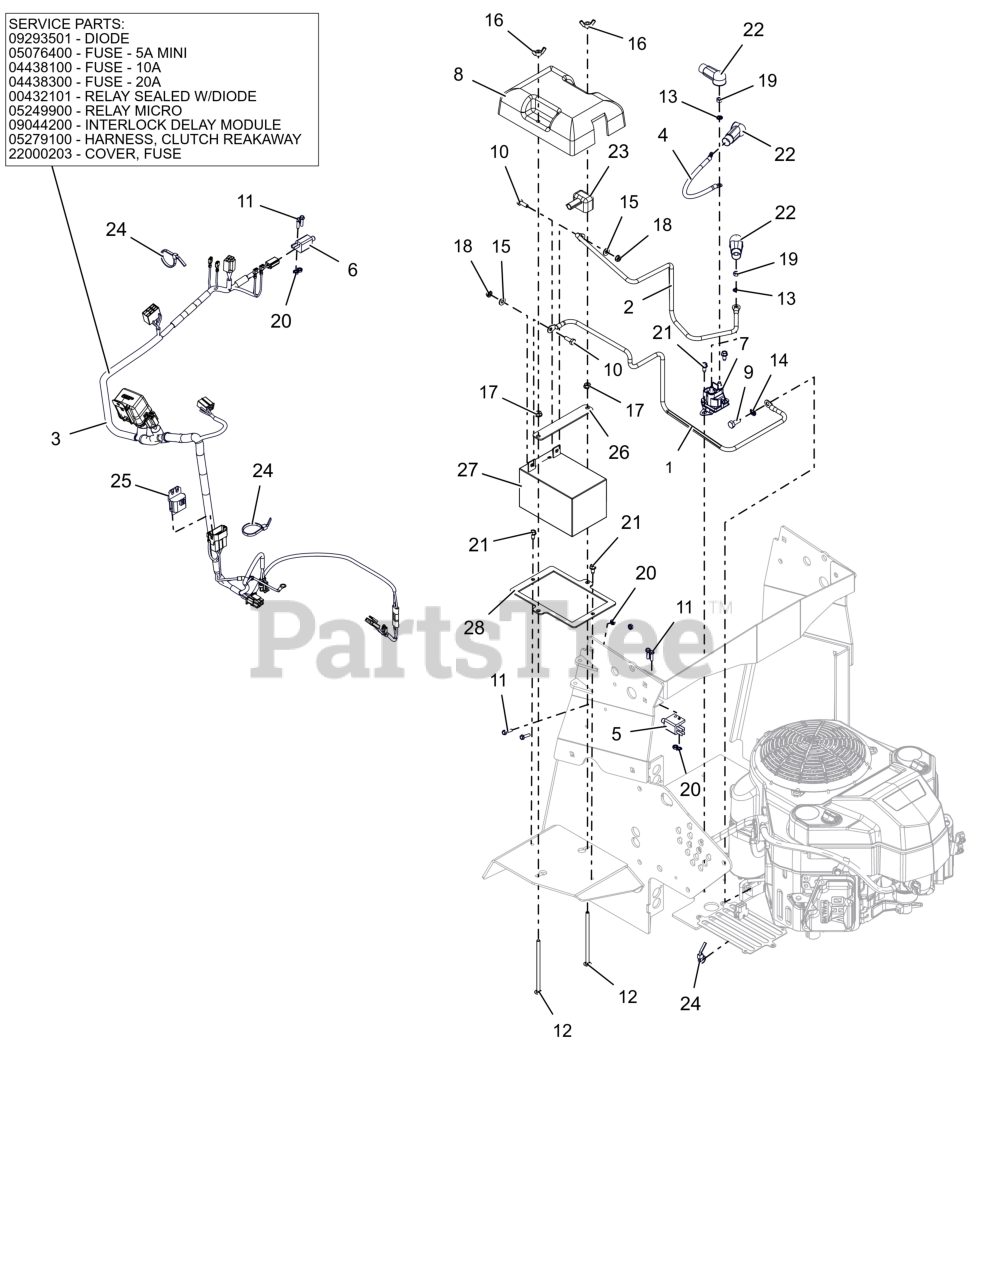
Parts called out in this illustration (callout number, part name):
1	CABLE, NEGATIVE BATTERY
2	CABLE, RED- .31X30.00 (6) X .25
3	HARNESS- WIRING
4	CABLE-POSITIVE BATTERY 9.00"
5	SWITCH- DOUBLE POLE N.O./N.O.
6	SWITCH- SINGLE POLE N.O.
7	SOLENOID, STARTER (SEALED)
8	COVER, BATTERY
9	BLT, HEX M8-1.25X20 G8.8 ZCC
10	BLT, HEX .25-20X.75 G5 ZCC
11	BLT, HWH #10-24X.75 ZCC
12	BLT- RHSN .25-20X5.0 ZCC
13	WSHR,LK-EXT.262X.502X.026 ZCC
14	WSHR,LK-EXT .326X.599X.031 ZCC
15	WSHR,FLT .281X.625X.065 ZCC
16	NUT- LK-WING .25-20 ZCC
17	NUT-LK-CTR-FLG .25-20 ZC120
18	NUT-KEPS .250-20 ZCC
19	NUT-STD M6-1.0 ZCC
20	NUT, KEPS #10-24 ZCC
21	SCR-TAP .25-20X.50 HWH ZCC
22	BOOT, .65ID POS
23	INSULATOR
24	CABLE TIE LG 5-1/2
25	MODULE,INTERLOCK,DELAY, 1801
26	BAR, BATTERY STRAP (BLACK)
27	BATTERY, 12V 12AH -190CCA
28	HOLDER- BATTERY
